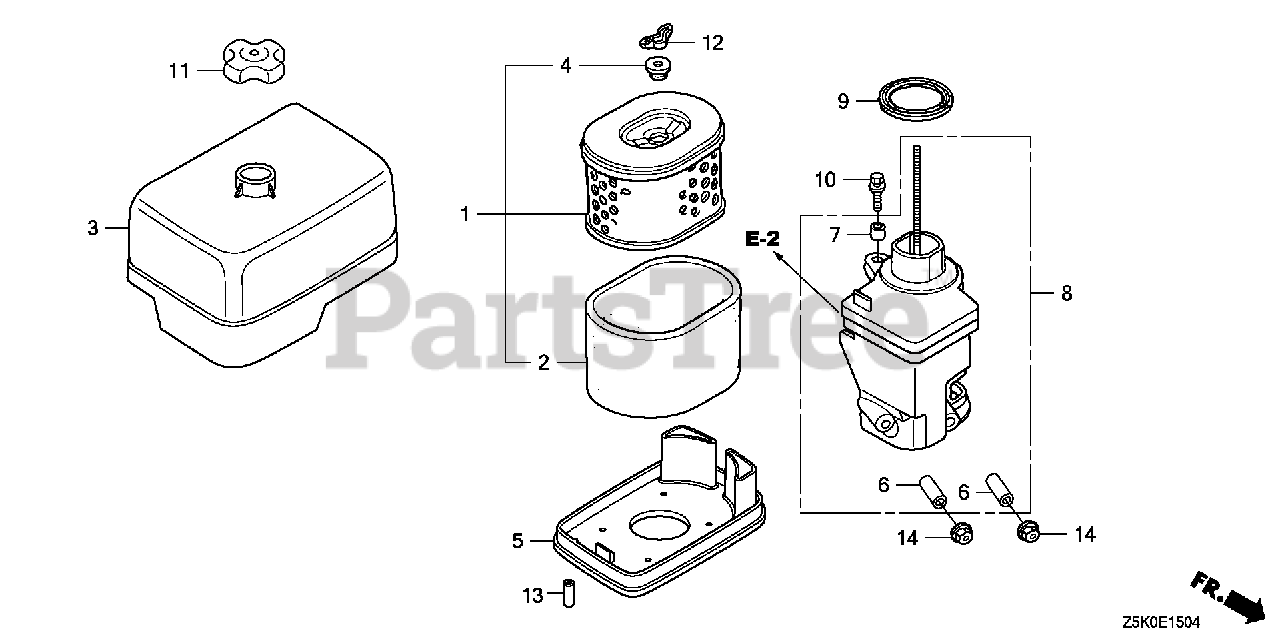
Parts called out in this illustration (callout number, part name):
1	ELEMENT, AIR CLEANER
2	FILTER (OUTER)
3	COVER, AIR CLEANER HOUSING
4	GROMMET, AIR CLEANER
5	NOSE, MUFFLER
6	COLLAR, AIR CLEANER
7	COLLAR B, AIR CLEANER
8	ELBOW, AIR CLEANER
9	GASKET, AIR CLEANER HOUSING
10	BOLT-WASHER (6X18)
11	NUT, AIR CLEANER COVER
12	WINGNUT, TOOL BOX SETTING
14	NUT, FLANGE (6MM)
